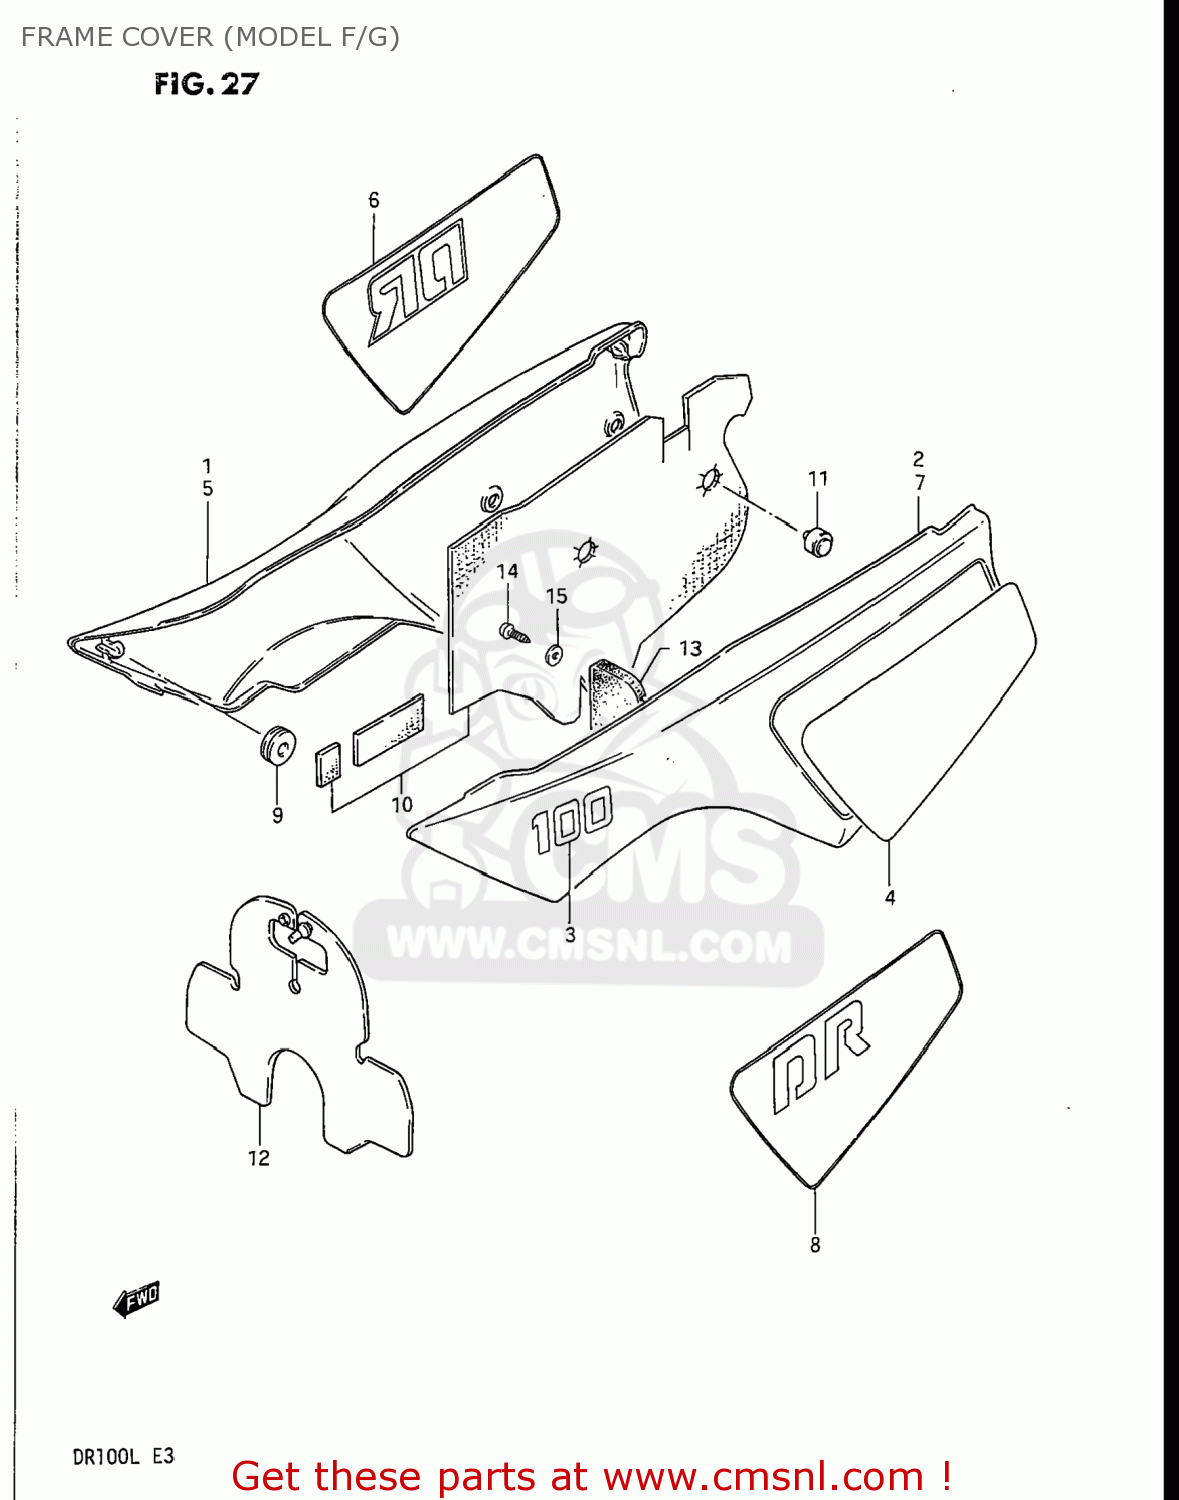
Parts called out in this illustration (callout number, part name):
1	COVER,FRAME,RIGHT
2	COVER,FRAME,LEFT
3	EMBLEM,FRAME COVER
4	EMBLEM,FRAME COVER,LEFT
5	COVER,FRAME,RIGHT
6	TAPE SET,FRAME COVER
7	COVER,FRAME,LEFT
8	TAPE SET,FRAME COVER
9	CUSHION
10	SHIELD SET,FRAME COVER H
11	CUSHION
12	MUD FLAP,FRONT
13	MUD GUARD,AIR CLEANER
14	SCREW
15	WASHER 4MM
